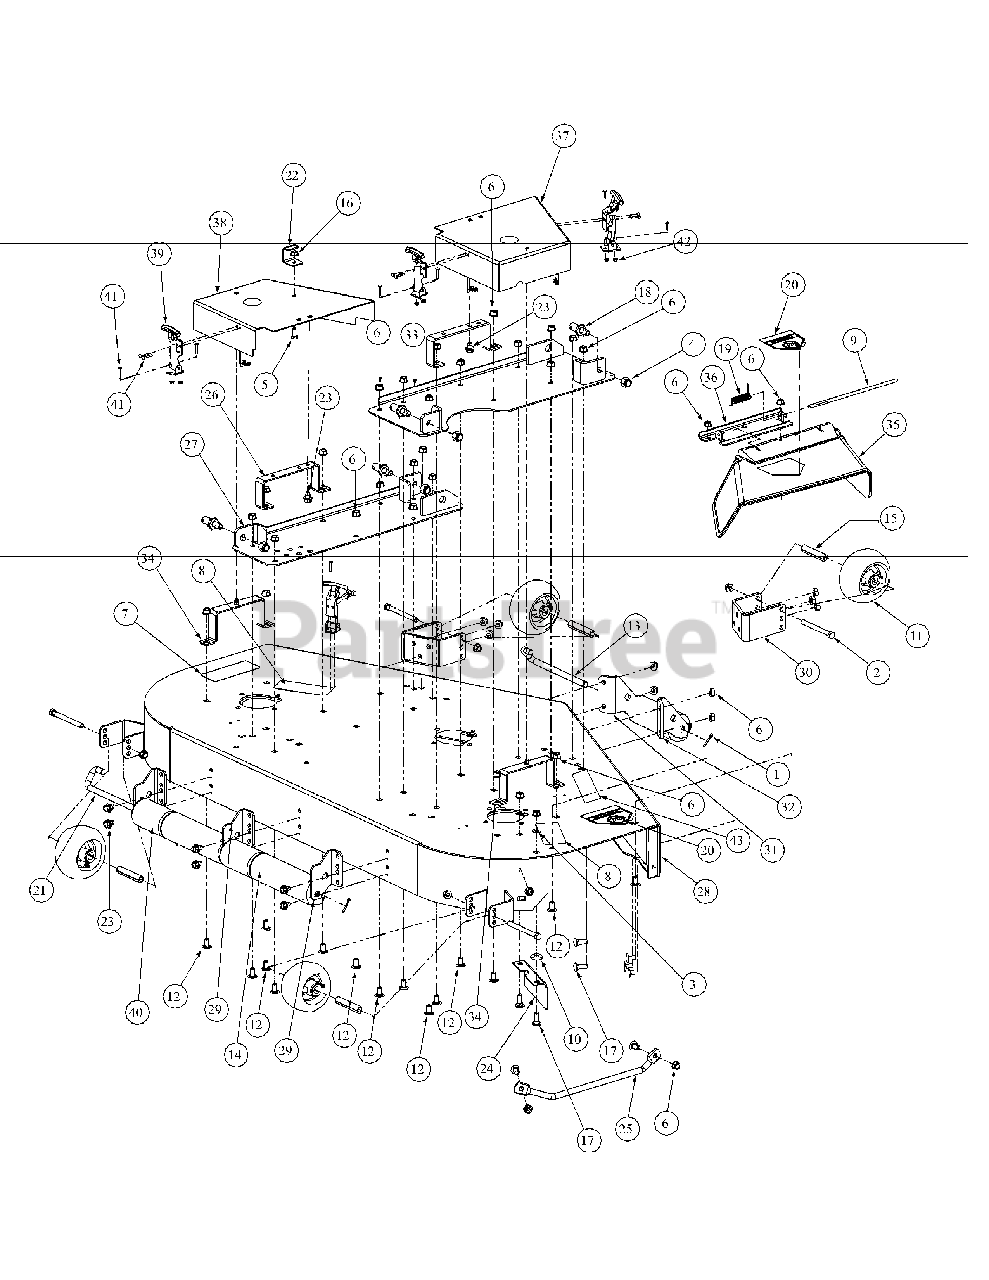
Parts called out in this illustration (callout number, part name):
1	Cotter Pin, .125 Dia. x 1.0
2	Hex Cap Screw, 3/8-16, 3.75
3	Flat Washer, 3/8
4	Lock Nut, Nylon Insert, 1/2-13
5	Hex Cap Screw, 5/16-18 x 3/4
6	Flange Lock Hex Nut, 3/8-16
7	Decal Rotating Blade
8	Decal Warning Shield Missing
9	Chute Deflector Rod
10	Idler Washer
11	Complete Wheel, 5.00 Dia
12	Carriage Bolt, 3/8-16 x .75 Lg
13	Roller Pin, 1/2 Dia x 7.31 Lg
14	Front Roller
15	Wheel Spacer
16	Hex Flange Lock Nut, 5/16-18
17	Carriage Bolt, 3/8-16 x 1
18	Pin, 5/8 Dia. x 1.2 Lg.
19	Torsion Spring, 0.4 ID x 2.16 LG
20	Decal, Danger Hands and Feet
21	Roller Rod
22	Bracket Stop Tension Rod
23	Hex Index Washer Screw, 3/8-16, .05
24	Fabricated Deck, Chute Bracket
25	Fabricated Deck Finger Guard
26	Fabricated Belt Support Cover
27	Left Hand Deck Bracket Assembly
28	48 Fabricated Deck Assembly
29	Fabricated Deck Roller Mount Bracket
30	Front Anti-Scalp Wheel Mount Bracket
33	Right Hand Deck Bracket Assembly
34	Outer Belt Cover Support Assembly
35	Deflector Chute
36	Deflector Chute Bracket
37	Right Hand Belt Cover
38	Left Hand Belt Cover
39	Latch Drawing, T-Handle
41	Phillip Head Screw, 10-32
42	Lock Nut, Nylon Insert, 10-32
